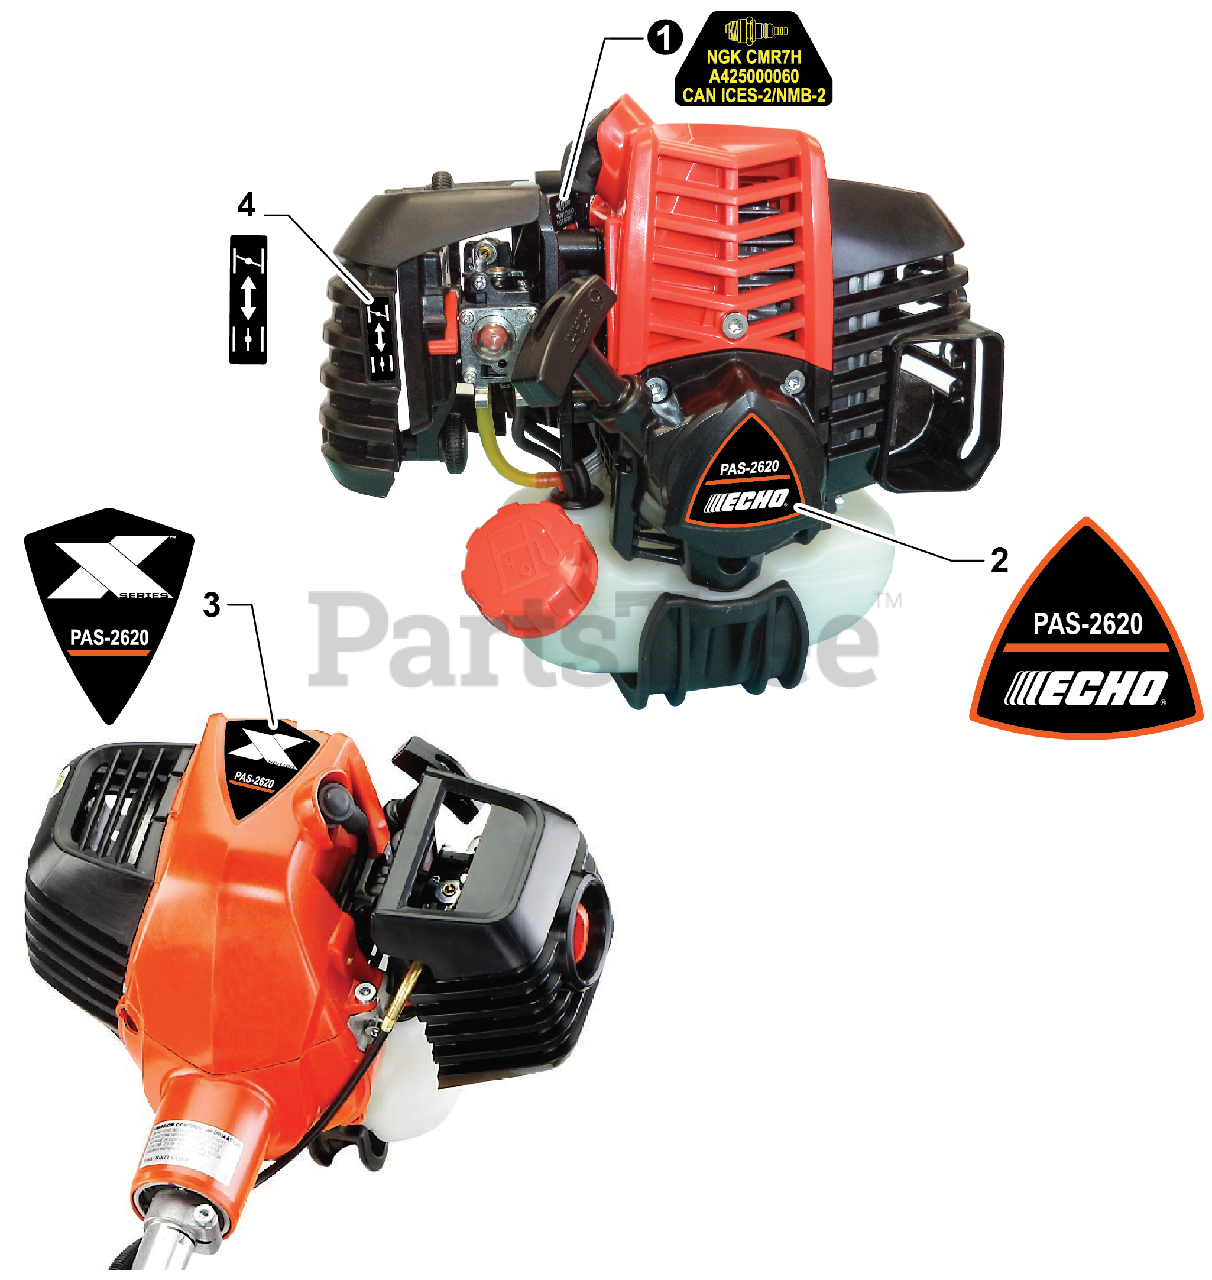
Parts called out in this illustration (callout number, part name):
1	LABEL, SPARK PLUG - CMR7H
2	LABEL, RECOIL STARTER - PAS-2620
3	LABEL - MODEL PAS-2620
4	LABEL, CHOKE
